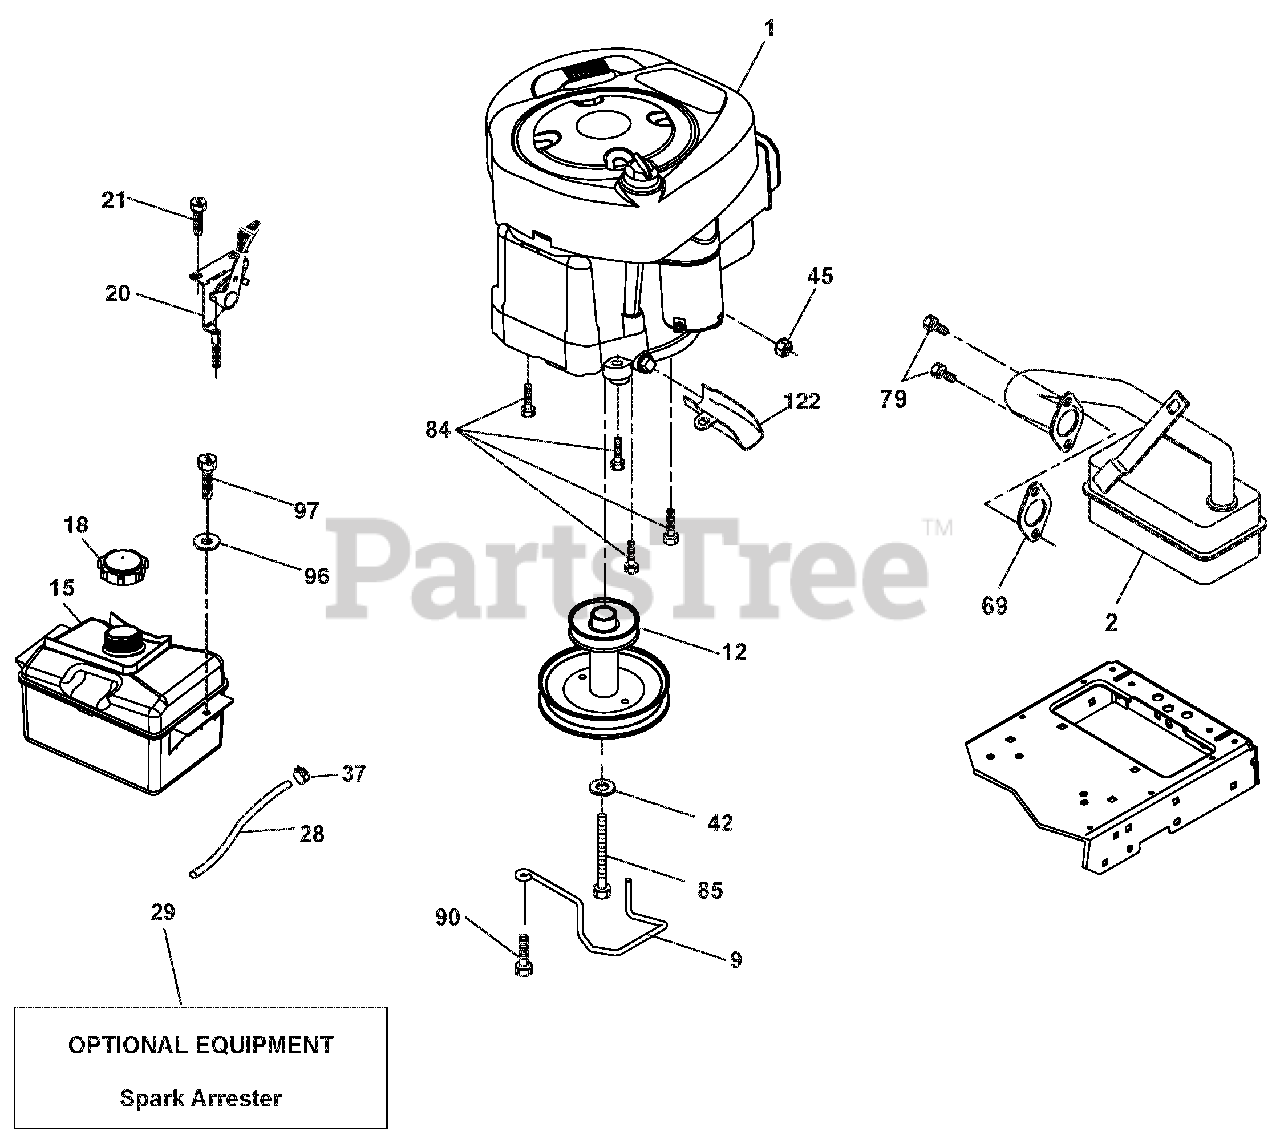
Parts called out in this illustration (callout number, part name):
1	ENGINE B&S MODEL NO. 21R807-0042-G1 (586508601) (ORDER PARTS FROM ENGINE MANUFACTURER.)
2	MUFFLER
9	KEEPER.BELT.ENGINE.3.25"NSTL
12	ENGINE PULLEY
15	TANK FUEL
18	CAP.FUEL
20	CONTROL.THROTTLE
28	LINE.FUEL.22"FRONT.EMIS.CA.LP
29	KIT.SPARK ARRESTOR(392390 B&S)
37	CLAMP.HOSE.BLK.
42	WASHER.LOCK.HVY HLCL.SPR.7/16
45	Nut, Keps Hex 1/4-20 unc
69	Gasket Eng 1 313 Id Tin Plated
79	SCREW SOCKET HEAD 5/16-18 X 1
84	Screw 3/8-16 x <
85	BOLT.HEX.7/16-20X4XGR5-1.5THR.
90	SCREW.3/8-16X1.SMGML.TAP/R.BLK
96	WASHER.9/32 X 7/8 X 16GA.
97	SCREW.HEXWSH.THDROL.1/4-20X3/4
122	Extension Drain Oil
